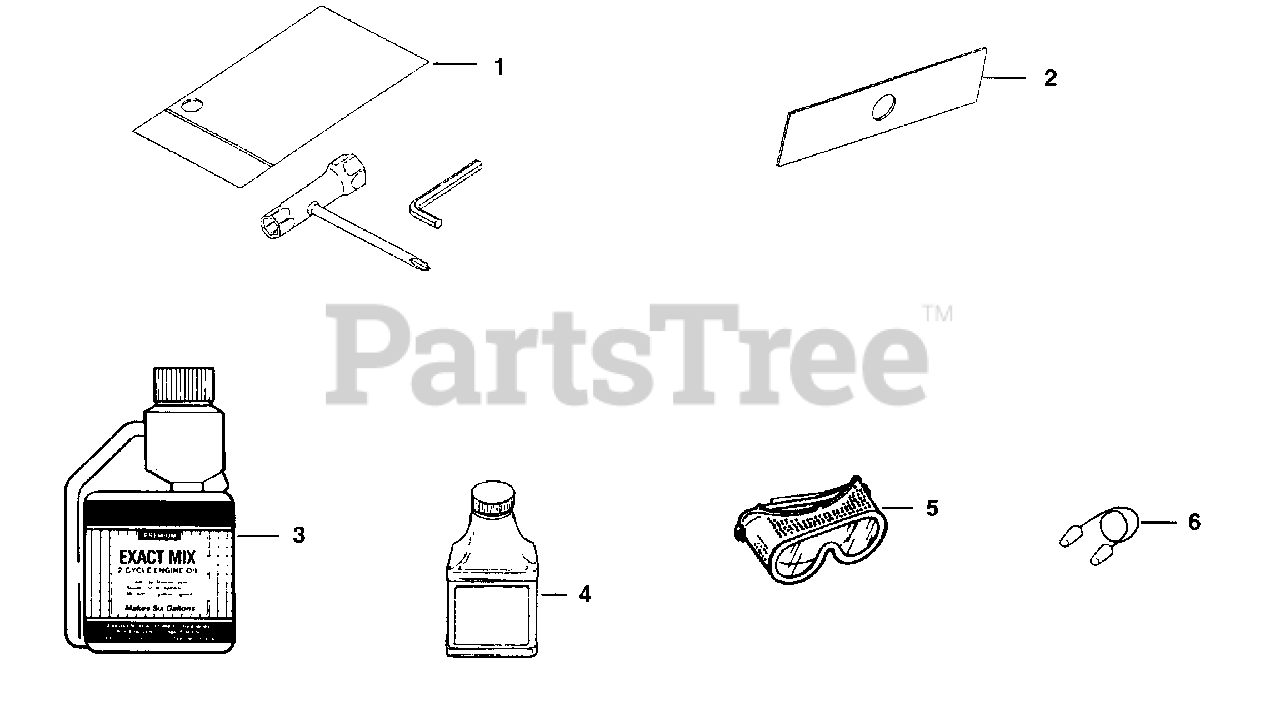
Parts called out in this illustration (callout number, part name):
1	TOOL KIT
3	EXACT MIX(TM) 16 oz
4	EXACT MIX(TM) 2.6 oz
6	EAR PLUGS
